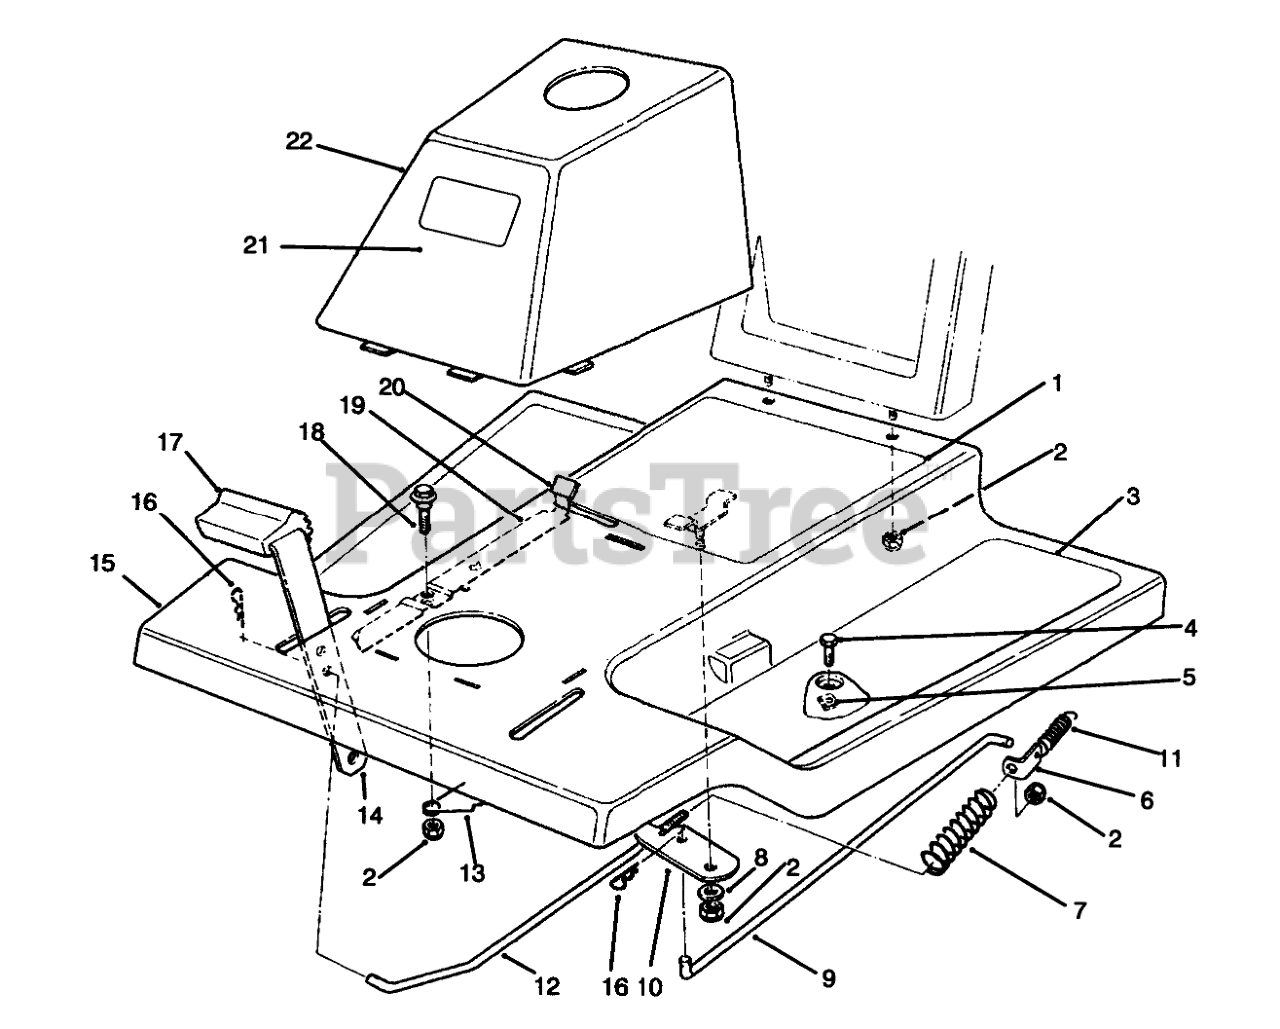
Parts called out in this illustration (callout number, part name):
1	DECAL - INSTRUCTION
2	NUT-LOCK, NI
3	TREAD-FOOT
4	SCREW-HH
5	NUT-TINNERMAN
6	BRACKET-BRAKE RETURN
7	SPRING-TRACTION BRAKE
8	WASHER-PIVOT
9	ROD-TRANS BRAKE
10	LEVER-BRAKE
11	SPRING-IDLER
12	ROD-FRONT BRAKE
13	SPRING-PARKING BRAKE
15	Body W.A.-Front
16	PIN-COTTER
17	PAD-PEDAL
18	SCREW-SHOULDER
19	PARKING BRAKE (BLACK)
20	TIP-PARKING BRAKE
21	DECAL
22	Tower (Incl. Ref. #21)
